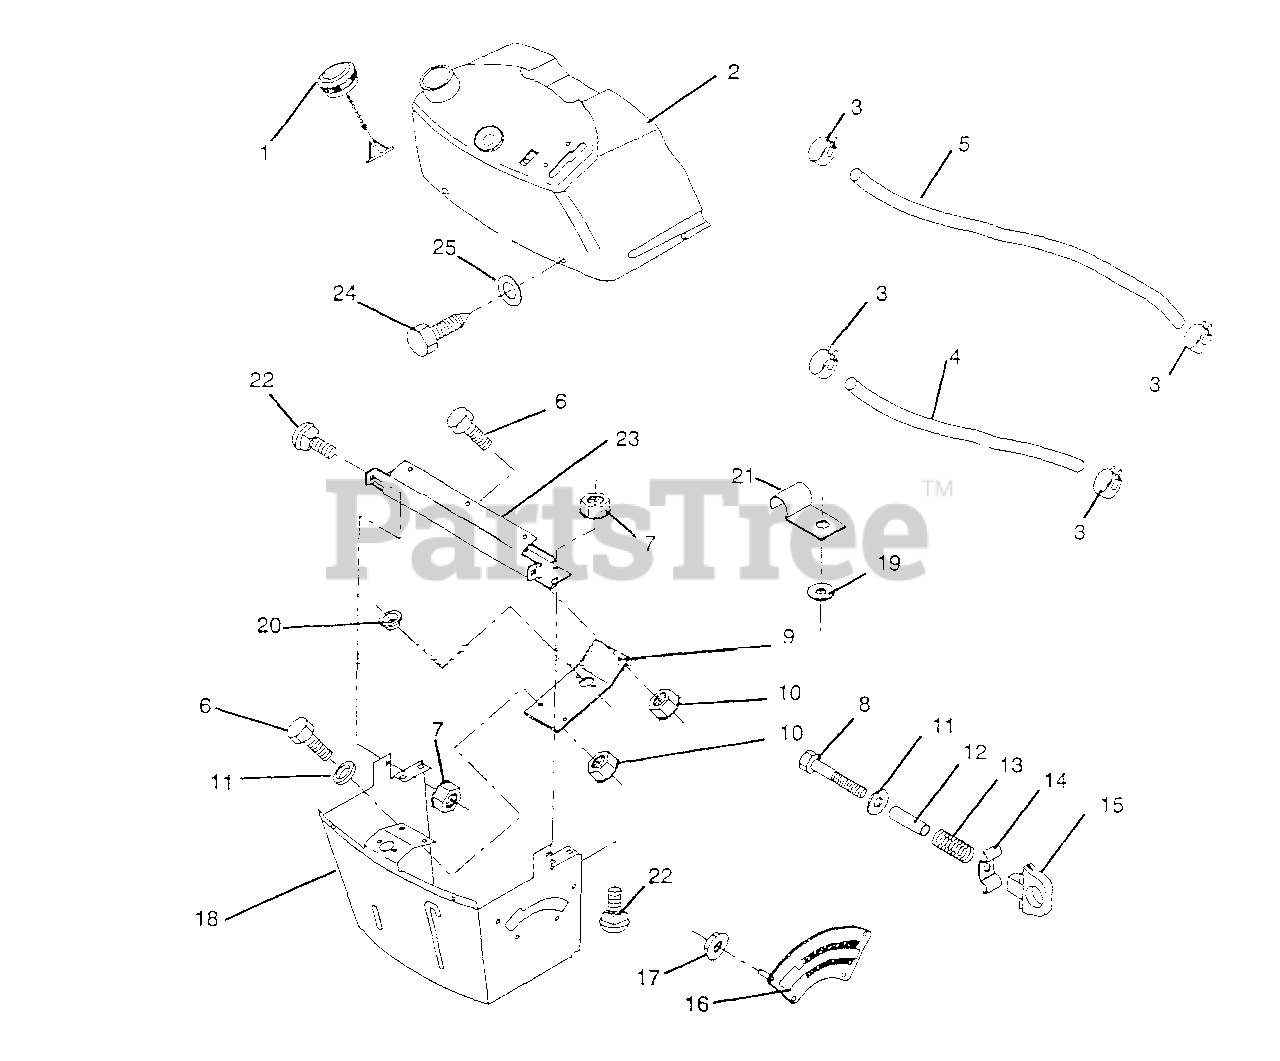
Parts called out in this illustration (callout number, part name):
1	Cap, Fuel
2	Assembly, Dash & Fuel Tank
3	Clamp, Hose
4	Line, Fuel
5	Line, Fuel
6	Bolt, Hex, 1/4-20 x 3/4
7	Nut, Hex Keps 1/4-20
8	Bolt, Fin. Hex 1/4-20 x 1 1/2
9	Plate, Support
10	Nut, Lock 1/4-20
11	Washer, 11/32 x 11/16 x 16
12	Spacer, Split
13	Spring
14	Knob, Height Retainer
15	Knob, Height Stop
16	Adjustment, Quadrant Height
17	Nut, Self Thread 3/16-18
18	Support, Dash
19	Washer 9/32 x 3/4 x 16 Ga.
20	Grommet, Split
21	Clip, Fuel line
22	Bolt, Carriage 1/4-20 x 1/2 Gr.5
23	Brace, Cross
24	Screw, Self Tapping 1/4-20 x 1 /2
25	Washer 9/32 x 1/2 x 16 Ga.
